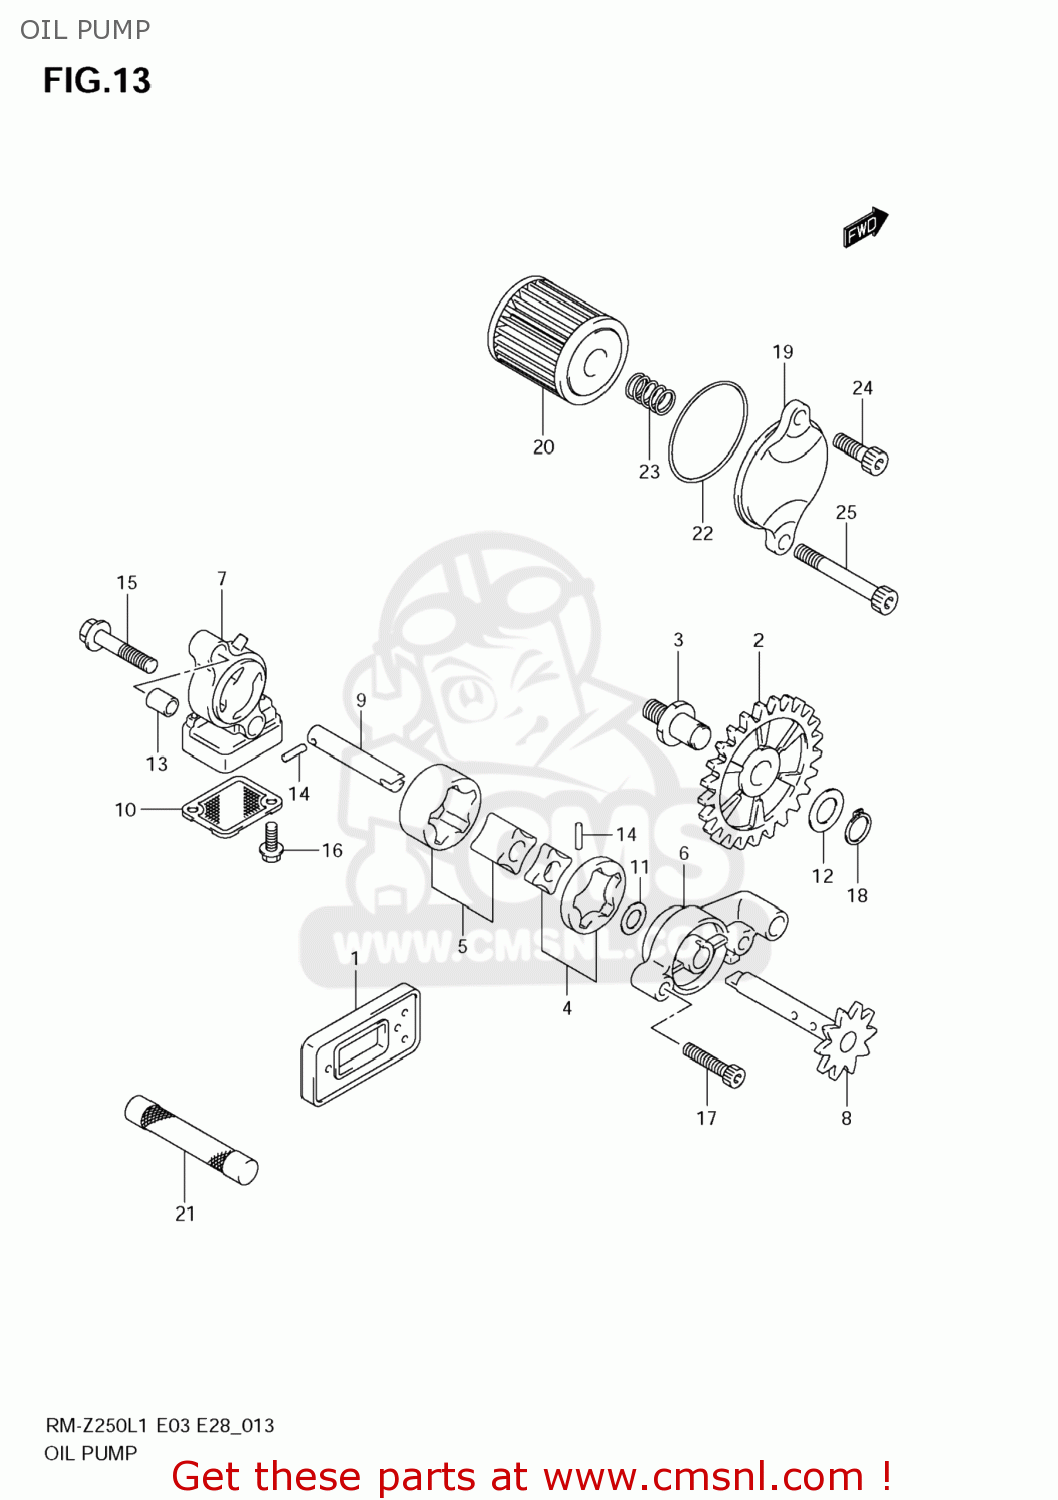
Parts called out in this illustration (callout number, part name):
1	VALVE ASSY,OIL REED
2	GEAR,OIL PUMP IDLE
3	SHAFT,OIL PUMP IDLE GEAR
4	ROTOR SET,OIL PUMP NO.1
5	ROTOR SET,OIL PUMP
6	COVER COMP,OIL
7	COVER,OIL PUMP NO.2
8	SHAFT,OIL PUMP DRIVEN GEAR
9	SHAFT,OIL PUMP NO.2
10	STRAINER,OIL PUMP NO.2
11	SHIM(8X12X0.8)
12	SHIM(10X18X0.5)
13	PIN(6.2X8X11)
14	PIN(2.5X11.8)
15	BOLT
16	BOLT
17	BOLT
18	CIRCLIP
19	CAP,ENG OIL FILTER OUTER
20	FILTER ASSY,ENGINE OIL
21	STRAINER,ENGINE OIL
22	O RING(D:2,ID:38.5)
23	SPRING
24	BOLT
25	BOLT
